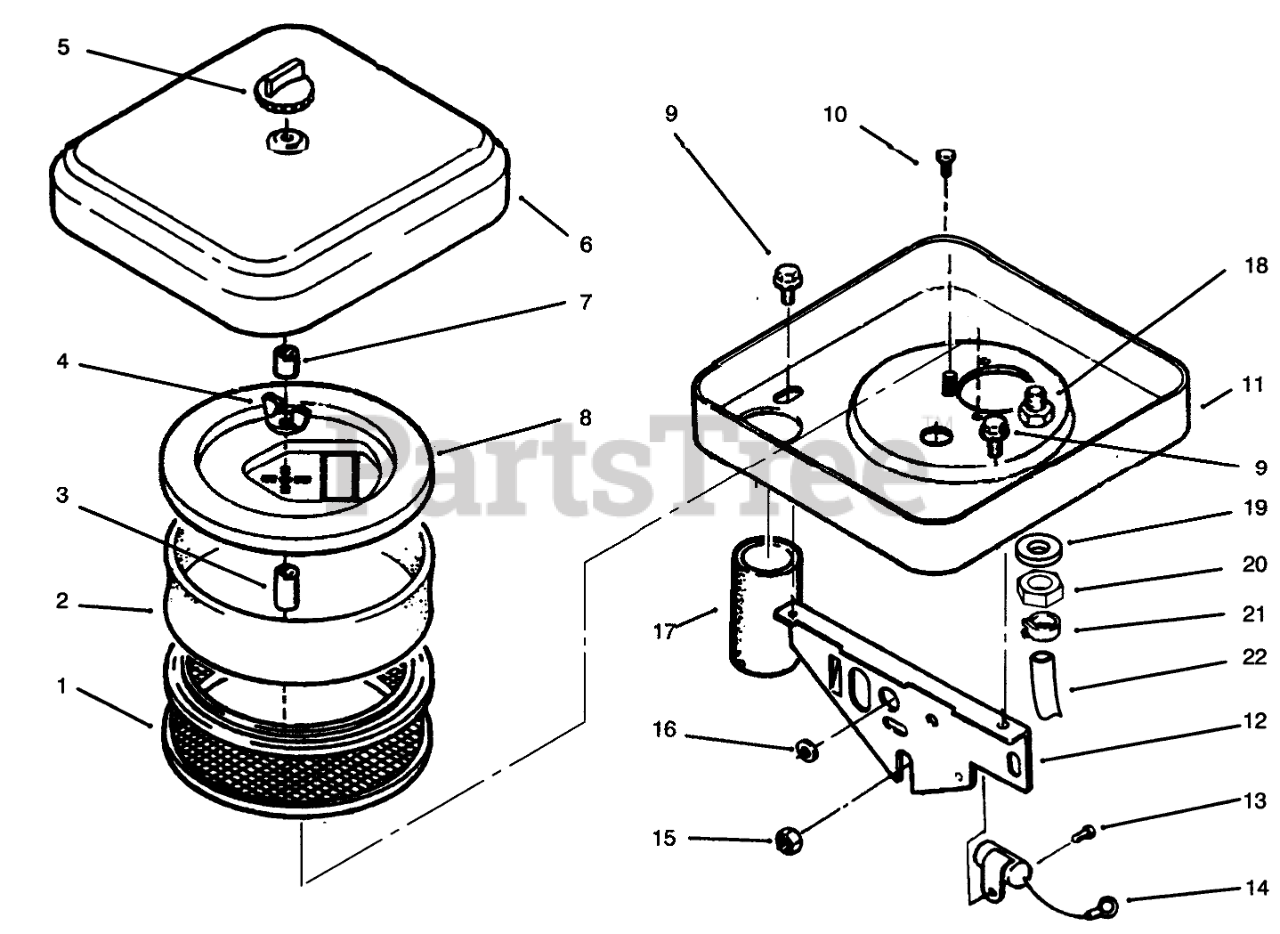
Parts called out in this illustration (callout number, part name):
1	AIR-CLEANER ELEMENT
2	AIR CLEANER ELEMENT
3	SPACER-1" LG
4	1/4-20 WING NUT
6	CHROME-AIR CLEANER
7	SPACER-RUBBER
8	ELEMENT COVER KIT
9	SCREW-TAPPING
10	MACHINE SCREW
11	AIR-CLEANER HOUSING
12	SUPPORT-AIR CLEANER
13	SCREW #10-32 X 5/8
14	CONDENSER
15	WASHER-LOCK
16	GROMMET
17	AIR INTAKE TUBE
18	Fitting-Barbed
19	HOSE FITTING GASKET
20	TAPPET NUT
21	CLAMP-HOSE
